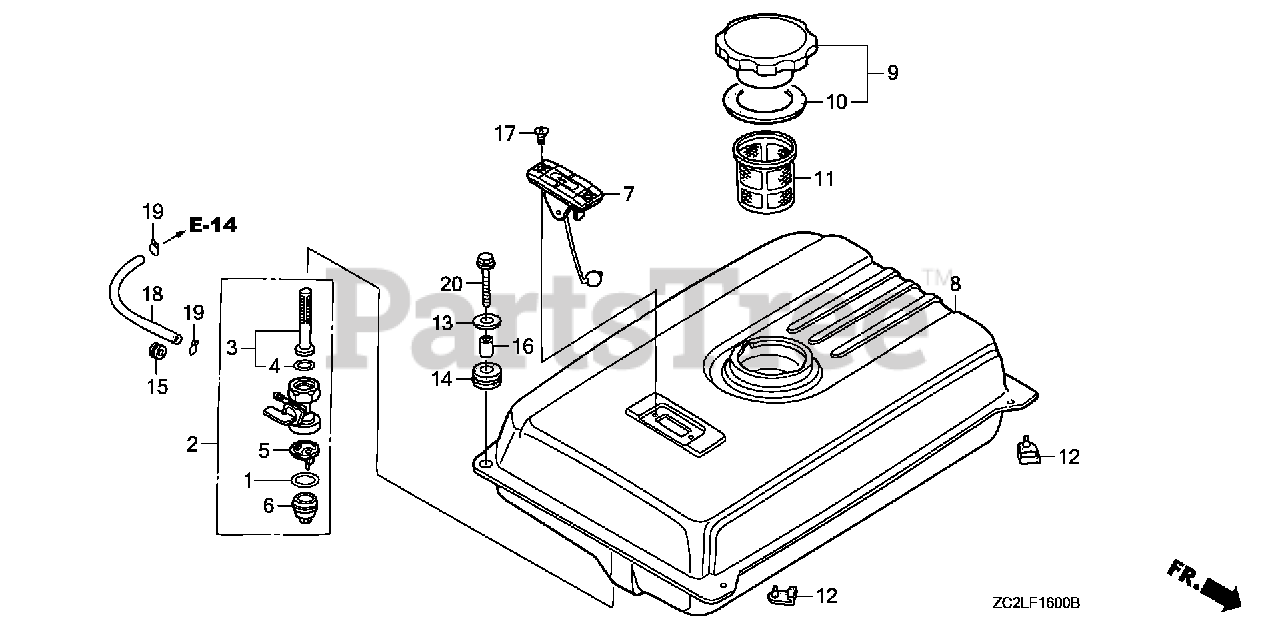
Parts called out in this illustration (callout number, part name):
1	GASKET, FUEL STRAINER CUP
2	PETCOCK ASSY.
3	SCREEN SET, FUEL STRAINER
4	O-RING (9.0X1.3)
5	FILTER, CUP
6	CUP, FUEL STRAINER
7	METER ASSY., FUEL
8	TANK, FUEL *R280* (POWER RED)
9	CAP, FUEL FILLER
10	GASKET, FUEL FILLER CAP
11	FILTER, FUEL
12	RUBBER, TANK MOUNTING
13	WASHER, TANK CUSHION
14	RUBBER, TANK CUSHION
15	RUBBER, FUEL (9X15X10)
15	RUBBER, FUEL (9X15X20)
16	COLLAR, TANK CUSHION
17	SCREW, FLAT (5X10)
18	BULK HOSE, FUEL (4.5X3000) (4.5X150)
19	CLIP, TUBE (B8)
20	BOLT, FLANGE (6X22)
